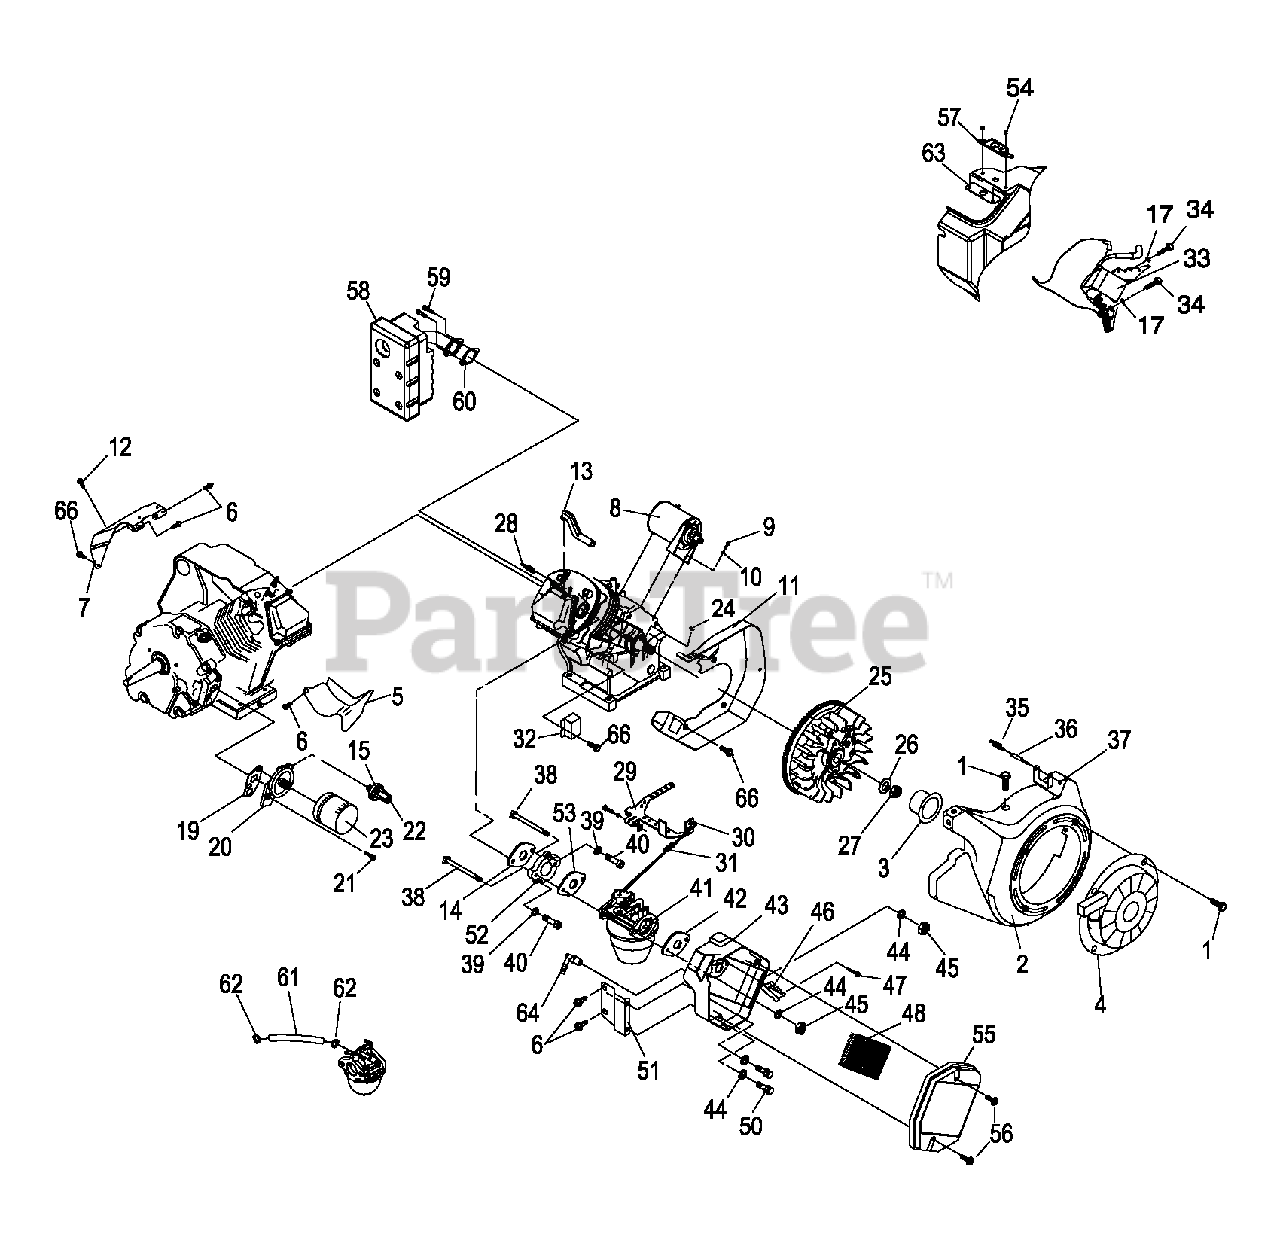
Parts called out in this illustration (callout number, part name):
1	SCREW HHTT M6-1.0 X 8 ZYC
2	ASSEMBLY, BLOWER HOUSING
3	PULLEY STARTER LARGE FRAME
4	RECOIL STARTER LARGE FRAME
5	WRAPPER, BOTTOM 12 HP HS
6	SCREW HHTT M6-1.0 X 10 YELLOW CHROME
7	WRAPPER, TOP REGULAR STEEL
8	ASSEMBLY, STARTER 46
9	SCREW SHC M8-1.25 X 40
10	WASHER, LOCK M8-5/16
11	BACKPLATE, W/ ELECTRIC START
12	SCREW, HHTT 5/16-18X1/2" CLEAR
13	HOSE, BREATHER GH410 ENGINES
14	GASKET, INTAKE ADAPTER
15	SCREW PPHM #8-32 X 1/4
17	WASHER, LOCK M6-1/4
19	GASKET,OIL FILTER ADAPTER
20	ADAPTER OIL FILTER W/TAPD HOLS
21	SCREW, SHC M8-1.25 X 30 G12.9
22	SWITCH, HOBBS OIL PRESSURE 5PSI
23	FILTER, OIL BLACK 75 LONG
24	KEY, WOODRFF 4 X 19D
25	FLYWHEEL, WITH RING GEAR 27 DEGREE
26	WASHER,BELV-20 X 2.2
27	NUT HEX M20-1.5 G8 YLW CHROME- FLYWHEEL
28	SPARKPLUG, CHAMPION RC14YC
29	ASSEMBLY,GOVERNOR LEVER 12HP
30	ROD, GOVERNOR CONTROL
31	SPRING, ANTI-LASH
32	OIL PRESSURE SHUTDOWN MODULE
33	ASSEMBLY, IGNITION ADV NO DIODE GH410
34	SCREW HHFC M6-1.0 X 25
35	SPRING GOVERNOR 320/360/410
36	BOLT, GOVERNOR ADJUSTMENT M5
37	NUT, HEX LOCK M5-0.8 NYLON INSERT ZINC
38	BOLT, CARBURETOR MOUNTING
40	SCREW, SHC M6-1.0 X 20 G12.9 ZINC PLATED
41	CARBURETOR ASSEMBLY, 410HS
42	GASKET, AIR CLEANER
43	BASE, ACLNR 410 XP PORT W/EVAP
44	WASHER, FLAT M6
45	NUT, HEX LOCK M6-1.0 NYLON INSERT
46	PLATE, SPITBACK
47	SCREW HWHTF 8-18 X 0.5 HI-LOW
48	ELEMENT, AIR FILTER
50	SCREW, HHC M6-1.0 X 16 W/ LOCK WASHER
51	BRACKET, AIR CLEANER
52	ADAPTER, "K"
53	GASKET, CARBURETOR/MANIFOLD
54	RIVET, 1/8"
55	COVER, AIR CLEANER 13GN
56	BOLT, AIR CLEANER COVER
57	BRACKET, CHOKE CABLE
58	MUFFLER 410 SIDE-OUT CARB
59	SCREW, SHC M8-1.25 X 20 G12.9
60	GASKET, EXHAUST
61	HOSE,1/4" SAE30R7 SETIFLEX 13"
62	CLAMP, HOSE WORM GEAR
63	BACK PLATE
64	BARBED EL 90 1/8NPT X 1/4 NY
66	SCREW HHFC M6-1.0 X 12
